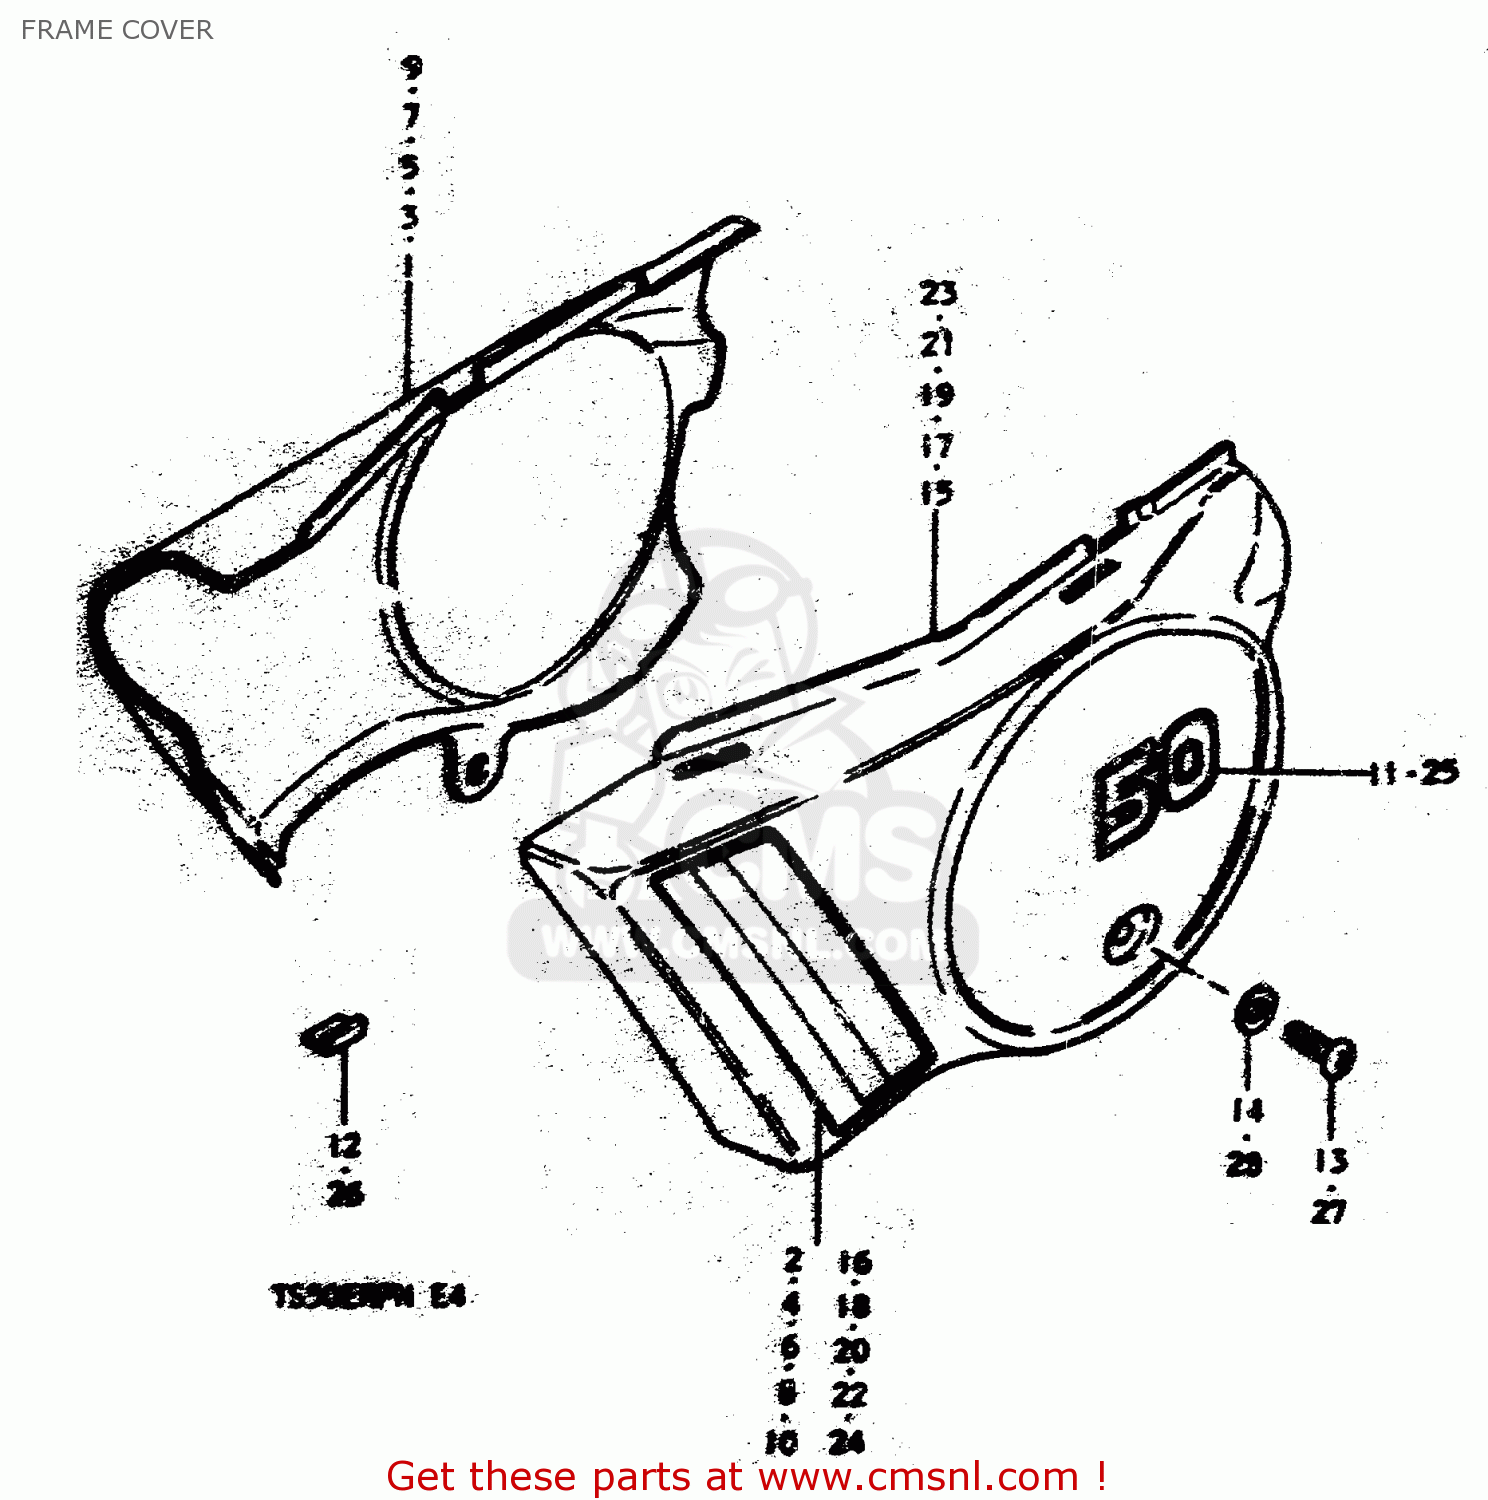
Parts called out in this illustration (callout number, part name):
1	COVER, FRAME RH (RED)
2	TAPE, STRIPING RH
3	COVER,FRAME RH
4	TAPE, STRIPING RH
5	COVER,FRAME RH
6	TAPE, STRIPING RH
7	COVER, FRAME RH
8	TAPE, STRIPING RH
9	COVER, FRAME RH (BLUE)
10	TAPE, STRIPING RH
11	EMBLEM, RH
12	CUSHION,FRAME COVER
13	SCREW 6X12
14	WASHER
15	COVER, FRAME LH (RED)
16	TAPE, STRIPING LH
17	COVER, FRAME LH (BLUE)
18	TAPE, STRIPING LH
19	COVER, FRAME LH (WHITE)
20	TAPE, STRIPING LH
21	COVER, FRAME LH
22	TAPE, STRIPING LH
23	CVOER, FRAME LH (BLUE)
24	TAPE, STRIPING LH
25	EMBLEM, OH
26	CUSHION,FRAME COVER
27	SCREW
28	WASHER
